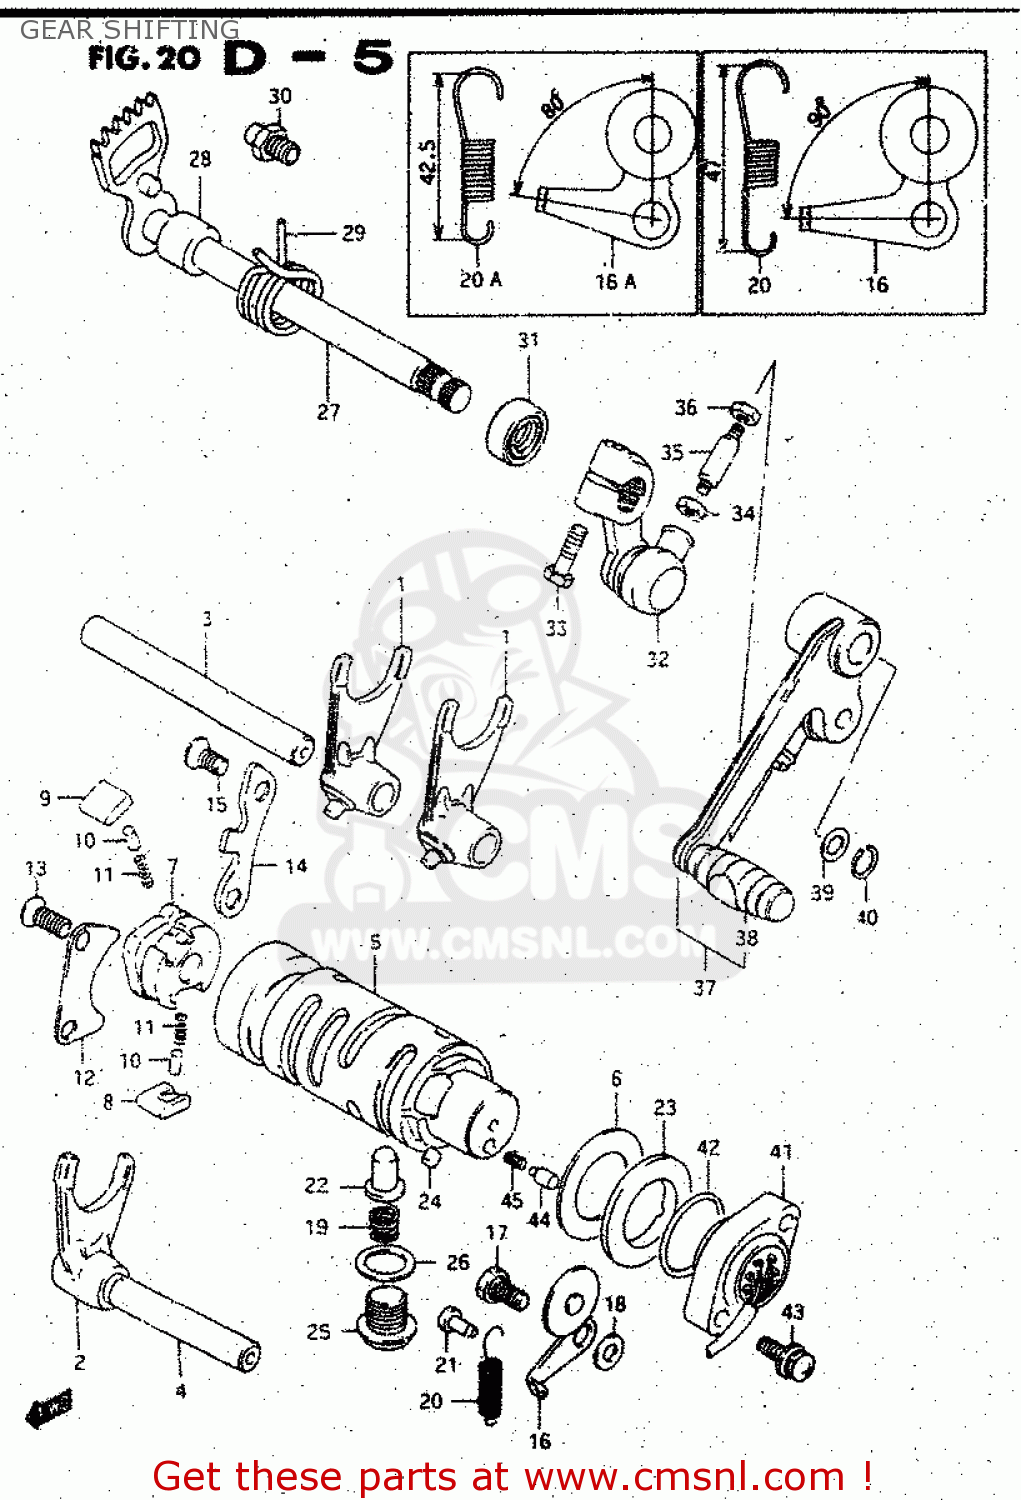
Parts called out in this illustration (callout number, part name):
1	FORK,GEAR SHIFT NO.2
2	FORK,GEAR SHIFT NO.3
3	SHAFT,GEAR SHIFT FORK
4	SHAFT,GEAR SHIFT FORK
5	CAM,GEAR SHIFT
6	WASHER,THRUST
7	GEAR,GEARSHIFT CAM DRIVE
8	PAWL,GEAR SHIFT NO.1
9	PAWL,GEAR SHIFT NO.2
10	PIN(5X8)
11	SPRING
12	LIFTER,GEAR SHIFT POLE
13	SCREW
14	GUIDE,GEAR SHIFT CAM
15	SCREW
16	STOPPER,GEAR SHIFTING
16A	STOPPER,GEAR SHIFT CAM
17	BOLT(6X14.6)
18	WASHER
19	SPRING
20	SPRING
20A	SPRING
21	RIVET
22	STOPPER,GEAR SHIFT CAM NO.2
23	PLATE,GEAR SHIFT CAM STOPPER
24	PIN 4X6
25	PLUG(14X12)
26	GASKET(14X19.2X2) (NAS)
27	SHAFT,GEAR SHIFT
28	SPACER(12X20X15.3)
29	SPRING
30	STOPPER,GEAR SHIFT CAM
31	OIL SEAL
32	ARM,GEAR SHIFT LINK
33	BOLT
34	NUT
35	ROD,GEAR SHIFT LINK
36	NUT
37	LEVER ASSY,GEAR SHIFT
38	RUBBER,GEAR SHIFT PEDAL
39	WASHER(12.5X20X1)
40	CIRCLIP,12 MM
41	TERMINAL BASE,NEUTRAL SWITCH
42	O-RING (D:2.4 ID:26.2)
43	SCREW
44	PIN(5X15.5)
45	SPRING
